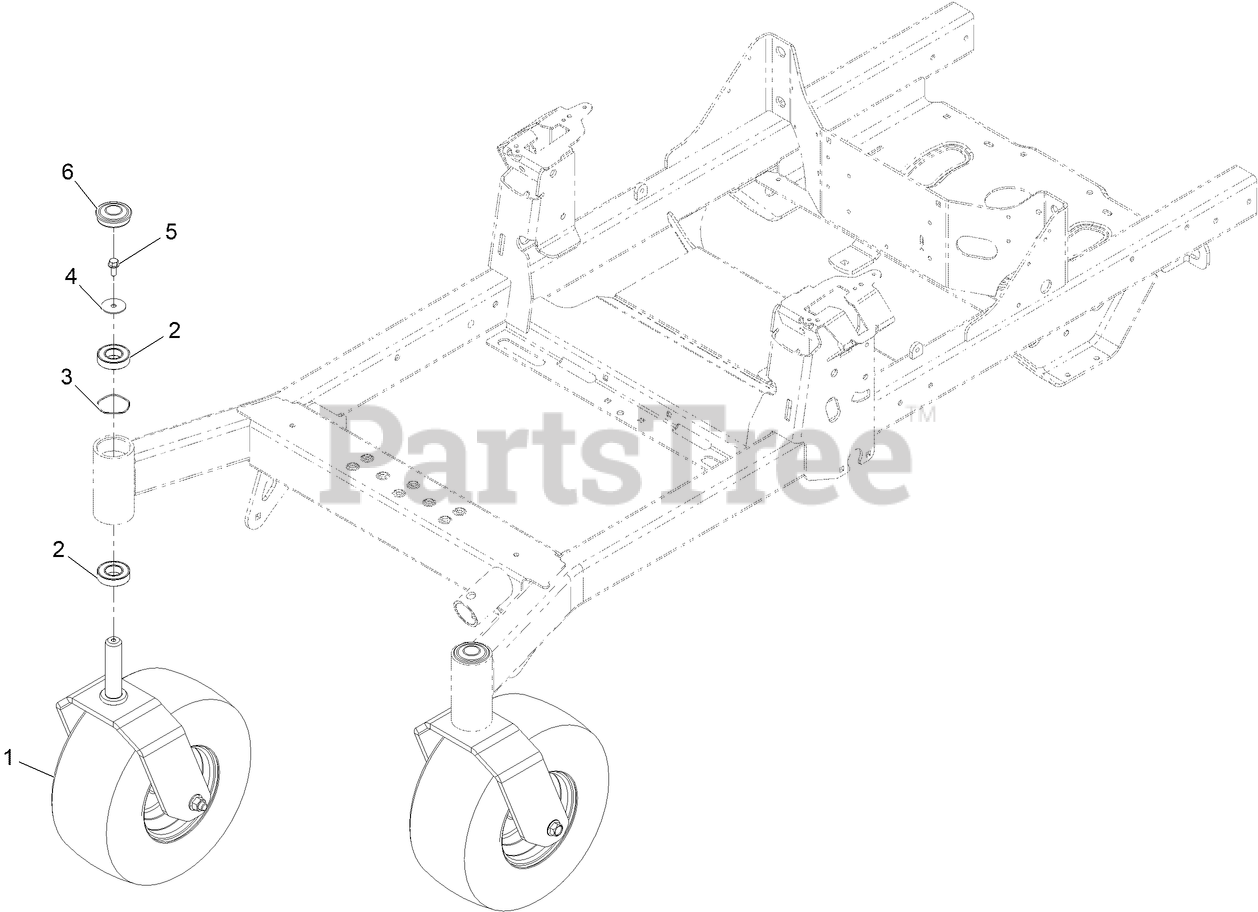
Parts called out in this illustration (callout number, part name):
1	ASM-Front Caster W/Fork
2	BEARING-BALL
4	WASHER-FLAT
5	SCREW-HHF
6	CAP, GREASE
